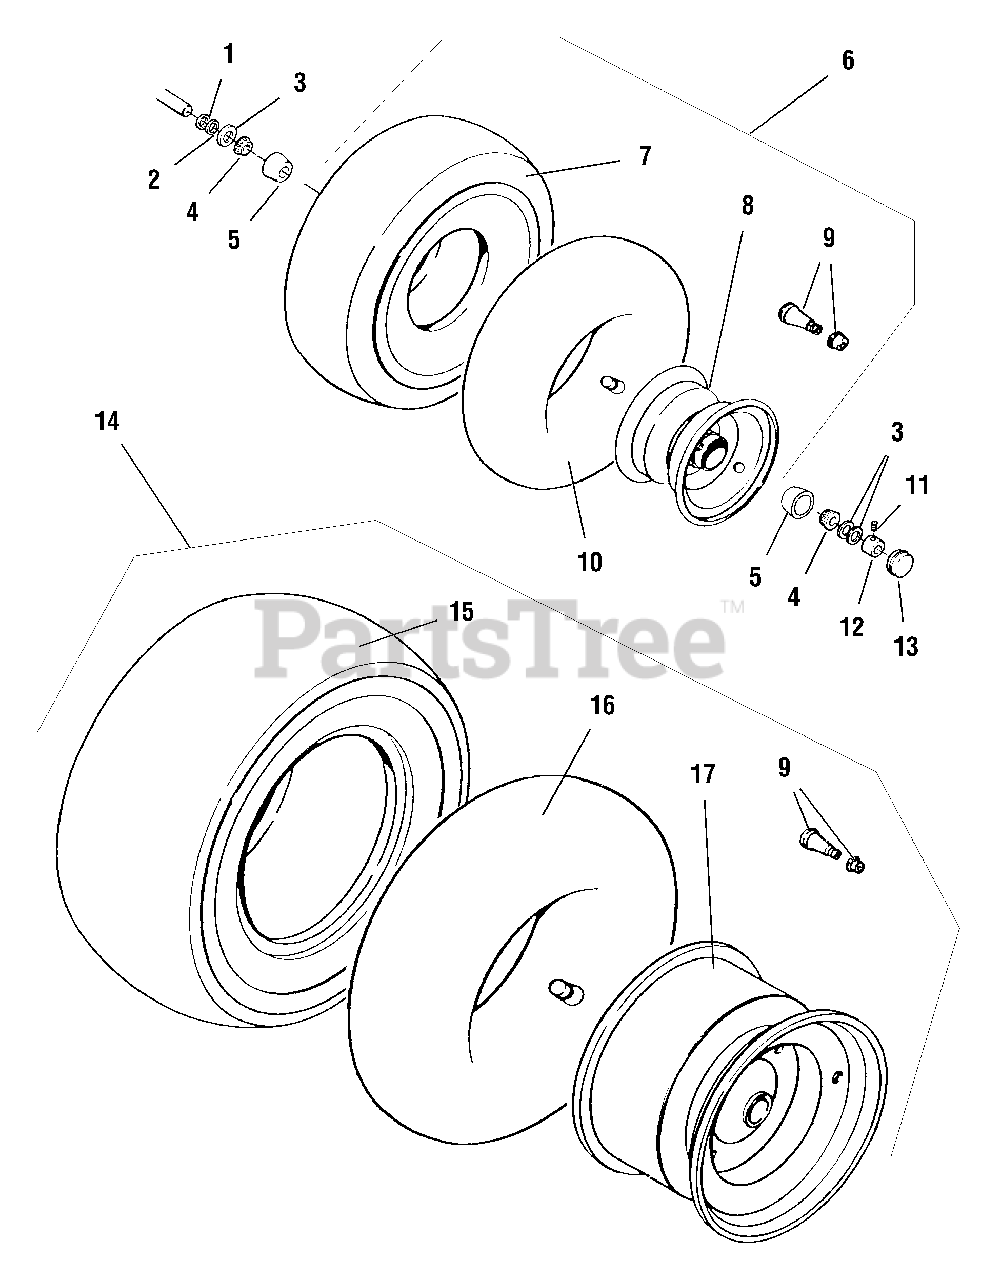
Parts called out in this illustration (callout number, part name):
2	WASHER, Plain, 49/64
4	BEARING, Tapered Roller
5	CUP, Bearing
6	FRONT WHEEL & TIRE ASSY., Metallic Gray, 16 x 6.50-8
7	FRONT TIRE, Dico, Multi Trac, 16 x 6.50
8	FRONT WHEEL ASSY., Metallic Gray
9	VALVE STEM & CAP ASSY.
10	FRONT TUBE, 16 x 6.50
11	SETSCREW, Sq. Hd.
12	COLLAR, Set
13	CAP, Hub
14	REAR WHEEL & TIRE ASSY., Metallic Gray, 23 x 10.50-12
15	REAR TIRE, Dico, Multi Trac, 23 x 10.50-12
16	REAR TUBE, 23 x 10.50-12
17	REAR WHEEL ASSY., Metallic Gray, 23 x 10.50-12
